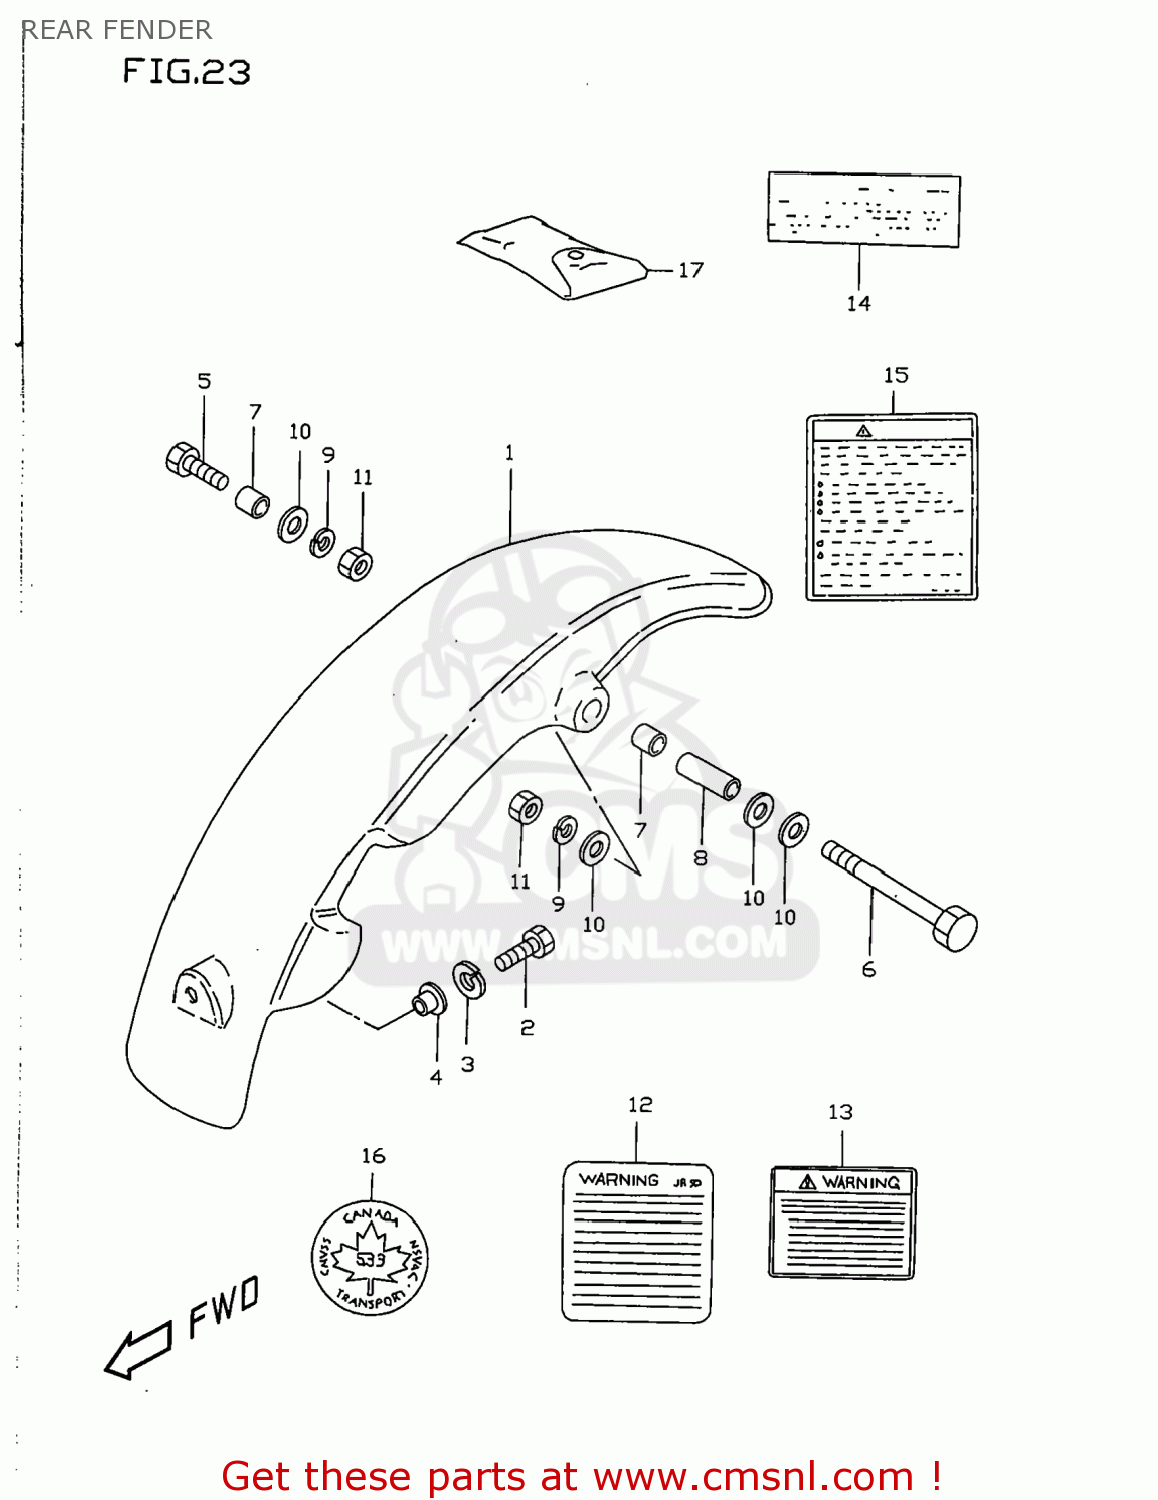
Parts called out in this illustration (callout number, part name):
1	FENDER,RR
2	BOLT
3	LOCK WASHER
4	WASHER
5	BOLT
6	BOLT, LH
7	SPACER,RR FENDER RR
8	SPACER (8.2X12.5X23.5)
9	LOCK WASHER
10	WASHER
11	NUT
12	LABEL,WARNING
13	LABEL,WARNING SAFETY
14	LABEL (MANUAL NOTICE)
15	LABEL, ATTENTION
16	PLATE
17	TOOL ASSY
18	MANUAL, OWNER'S
